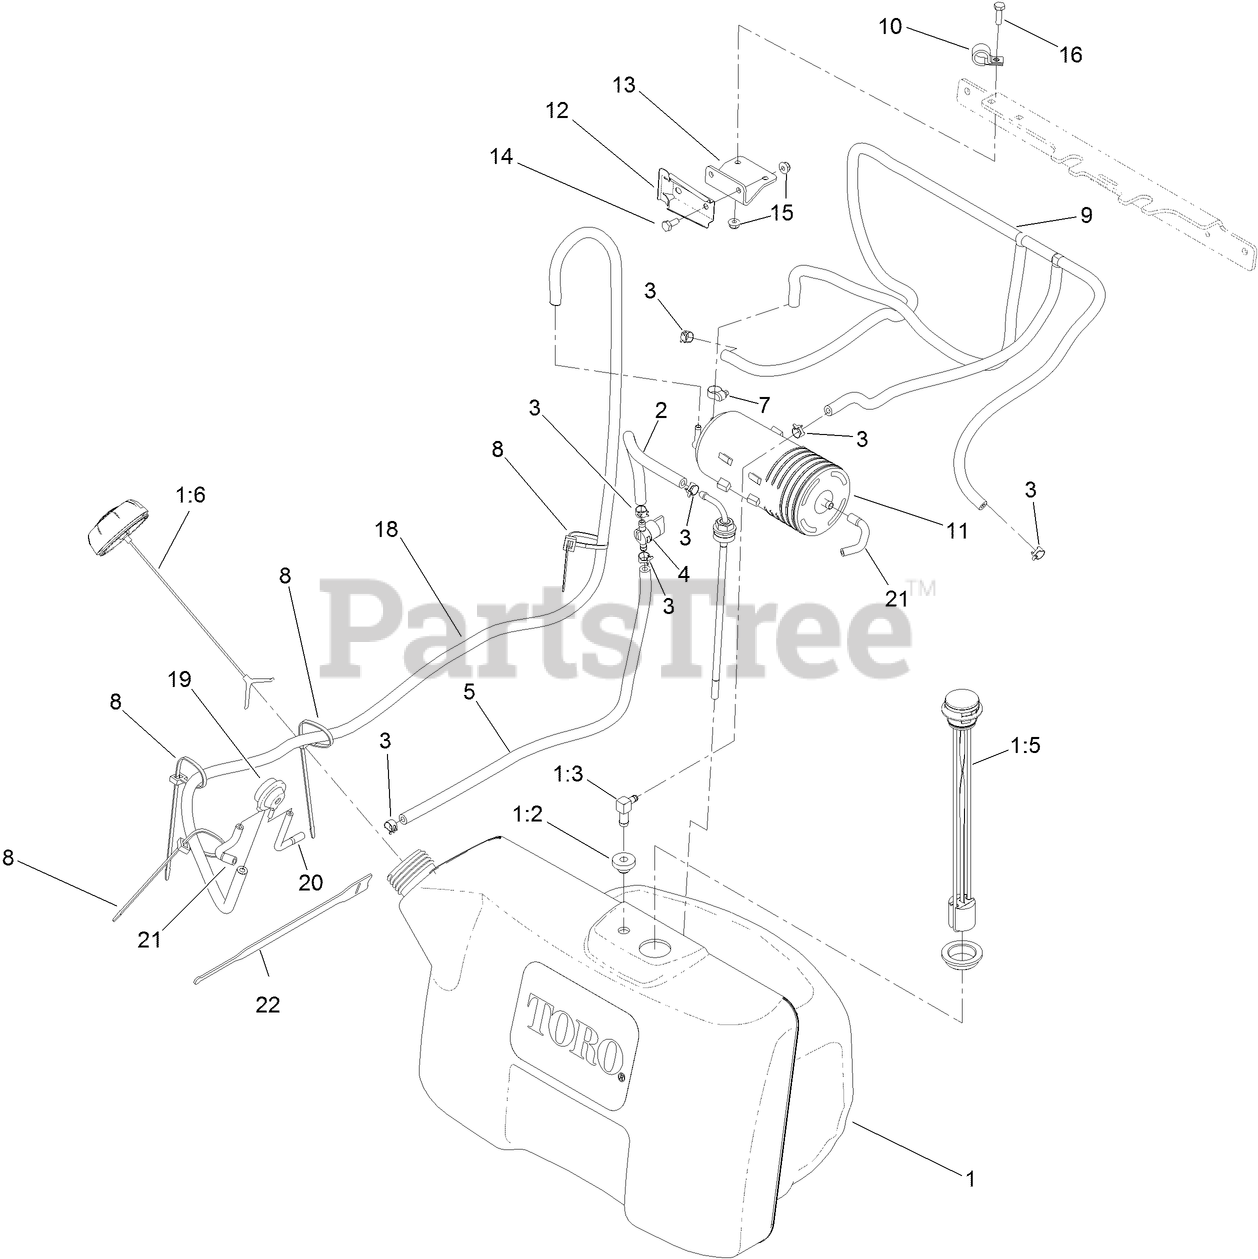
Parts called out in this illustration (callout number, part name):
1	TANK ASM
1:2	BUSHING
1:3	ELBOW-90 DEG
1:5	CAP-FUEL, RATCHETING
1:6	FITTING-FUEL, BULKHEAD
2	HOSE-FUEL
3	CLAMP-HOSE
4	VALVE-FUEL
5	HOSE-FUEL
7	CLAMP-WORM
8	TIE-CABLE
9	VENT HOSE ASM
10	CLAMP-CABLE
11	CANISTER-CARBON, 800CC
12	BRACKET-CANISTER, CARBON
13	BRACKET-CANISTER
14	SCREW-HH
15	NUT-HF
16	SCREW-HH
18	HOSE-FUEL
19	VALVE-CONTROL, VACUUM
20	HOSE-VENT, FORMED
21	HOSE-VENT, FORMED
22	STRAP-VELCRO, CABLE TIE
